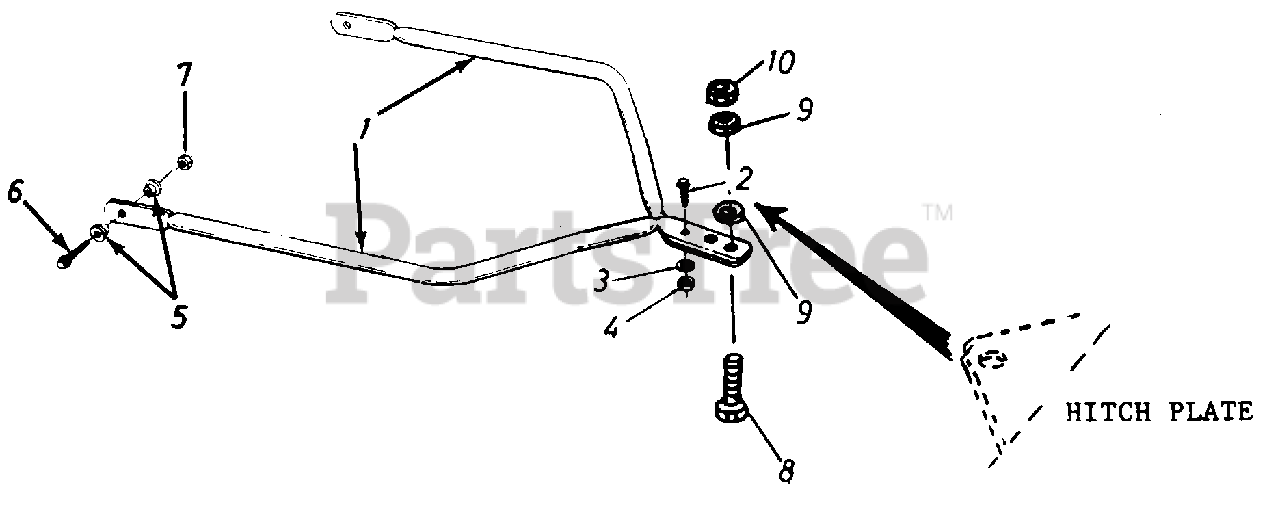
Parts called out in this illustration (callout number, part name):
3	L.-Wash. 1/4" I.D.
4	Hex Nut 1/4-20 Thd.*
5	Shoulder Spacer
6	Hex Wash. Hd. Self-Tapp Scr. 5/16-18 x 1.0" Lg.
7	Hex Nut 5/16-18 Thd.
8	Shld. Bolt .496 Dia.
9	Belle-Wash. .39 I.D. x 1.12 O.D.
10	Hex Jam L-Nut 3/8-16 Thd.
